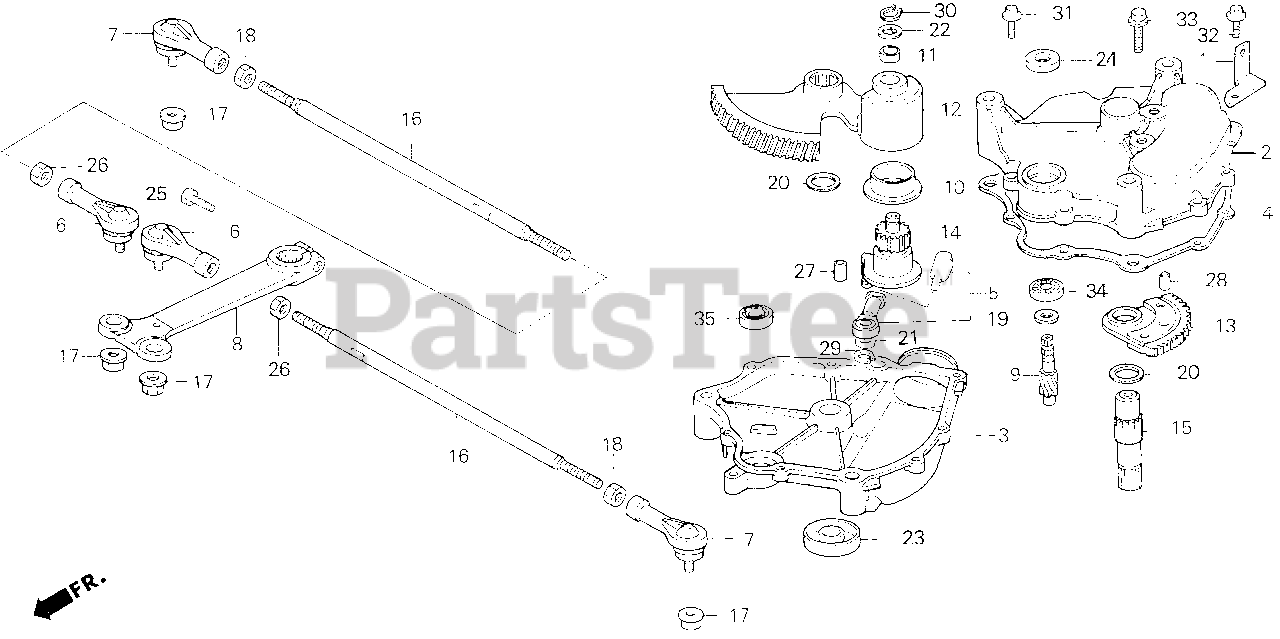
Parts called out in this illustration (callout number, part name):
1	BRACKET, HARNESS CLIP (A)
2	CASE, STEERING GEAR (UPPER)
3	CASE, STEERING GEAR (LOWER)
4	GASKET, STEERING CASE
5	JOINT, ROD END
6	JOINT, R. BALL (ER10)
7	JOINT, L. BALL (ER10)
8	ARM, PITMAN
9	PINION, STEERING
10	BUSH, PINION HOLDER (A)
11	BUSH, PINION HOLDER (B)
12	GEAR, STEERING
13	GEAR, SUN (67T)
14	GEAR, PLANETARY (19T)
15	SHAFT, STEERING SECTOR
16	TIE ROD, FR.
17	NUT, SELF-LOCK (10MM)
18	NUT, L. HEX. (10MM)
19	WASHER, THRUST (15MM)
20	WASHER, THRUST (25MM)
21	WASHER, THRUST (12MM)
22	WASHER (16.5X26X2)
23	OIL SEAL (25X38X7) (ARAI)
24	OIL SEAL (15X28X7)
25	BOLT, HEX. (10X40)
26	NUT, HEX. (10MM)
27	PIN, DOWEL (14X20)
28	PIN, DOWEL (10X16)
29	CIRCLIP, OUTER (12MM)
30	CIRCLIP (OUTER) (16MM)
31	BOLT, FLANGE (6X25)
32	BOLT, FLANGE (6X28)
33	BOLT, FLANGE (10X30)
34	BEARING, RADIAL BALL (6002UU)
35	BEARING, RADIAL BALL (6201)
